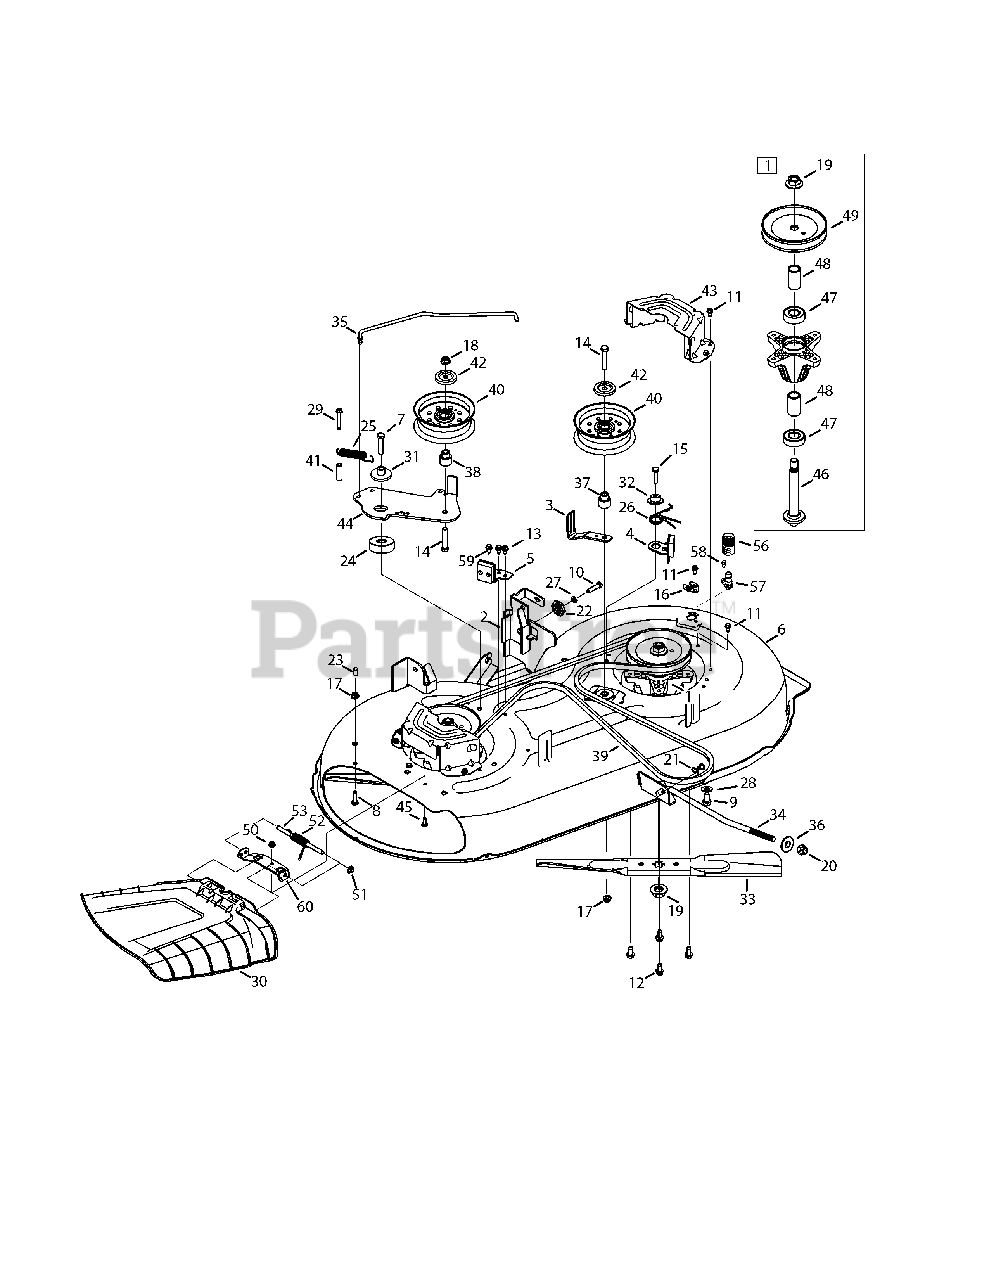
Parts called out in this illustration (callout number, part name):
1	Spindle Ass’y, Pulley, 6.2 Dia
2	Bracket Ass’y, Deck, Hanger LH
3	Belt Keeper
4	Brake Assembly, Deck, LH
5	Brake Assembly, Deck, RH
6	Deck, 42", w/o wheel brackets
7	Hex Screw, 3/8-16 x 1.75
8	Hex Cap Screw, 5/16-18 x 1.00
9	Screw, Self-tapping, 5/16-18, .750
10	Hex Screw, 5/16-18, 1.25, Gr5, Std
11	Screw, Self-tapping, 1/4-20, 0.500
12	Screw, 5/16-18 x 0.750
13	Screw, M6-1 x .625
14	Hex Screw, 3/8-16, 2.00, Gr8, Std
15	Hex cap Screw, 5/16-18 x 1.25
16	Deck Wash Plug
17	Nut, Flange Lock, 5/16-18, Grf
18	Nut, Flange Lock, 3/8-16, Grf
19	Nut, Flange, 5/8-18
20	Flange Lock Nut, 1/2-13
21	Bow-Tie Cotter Pin
22	Gear, Deck, Adjustment
23	Cap, .290 x .500
24	Spacer, .385 x 1.75 x .585
25	Extension Spring, .750 X 4.77
26	Torsion Spring, LH
27	Washer, Lock, 5/16, Regular Duty
28	Flat Washer, .406 x .875 x .059
29	Screw, Self Tapping, 1/4-20, 1.50
30	Chute Deflector Assembly
31	Shoulder Spacer, .970 x .190
32	Shoulder Spacer, .75 x .145
33	Blade, Cut, 21.23" 2-In-1
34	Rod, Lift, Deck, Frt, 12.7
35	Brake Rod
36	Deck Lift Pivot Cup
37	Shoulder Spacer, Idler
38	Shoulder Spacer, Pivot Idler
39	Belt, V Type, A Sec X 96.5
40	Pulley, Idler, 4.50"Dia
41	Spacer, .260 x .375 x 1.030
42	Pulley Cap
43	Deck Belt Cover, 42
44	Deck Idler Bracket
45	Hex Cap Screw, 1/4-20 x .62
46	Shift, Spindle, 6.11.
47	Bearing, Ball, .787id x 1.85 Odx.551
48	Spacer, .792 x 1.060 x 1.860
49	Pulley, Deck, 5.4 Dia
50	Nut, Flange Lock, 1/4-20, Nylon
51	Push Cap
52	Spring, Torsion, .440 ID x 1.75
53	Hinge Pin
56	Water Nozzle Adapter
57	Deck Wash Nozzle
58	Shoulder Screw, 1/4-20 x 0.50
59	Shoulder Screw, 1/4-20
